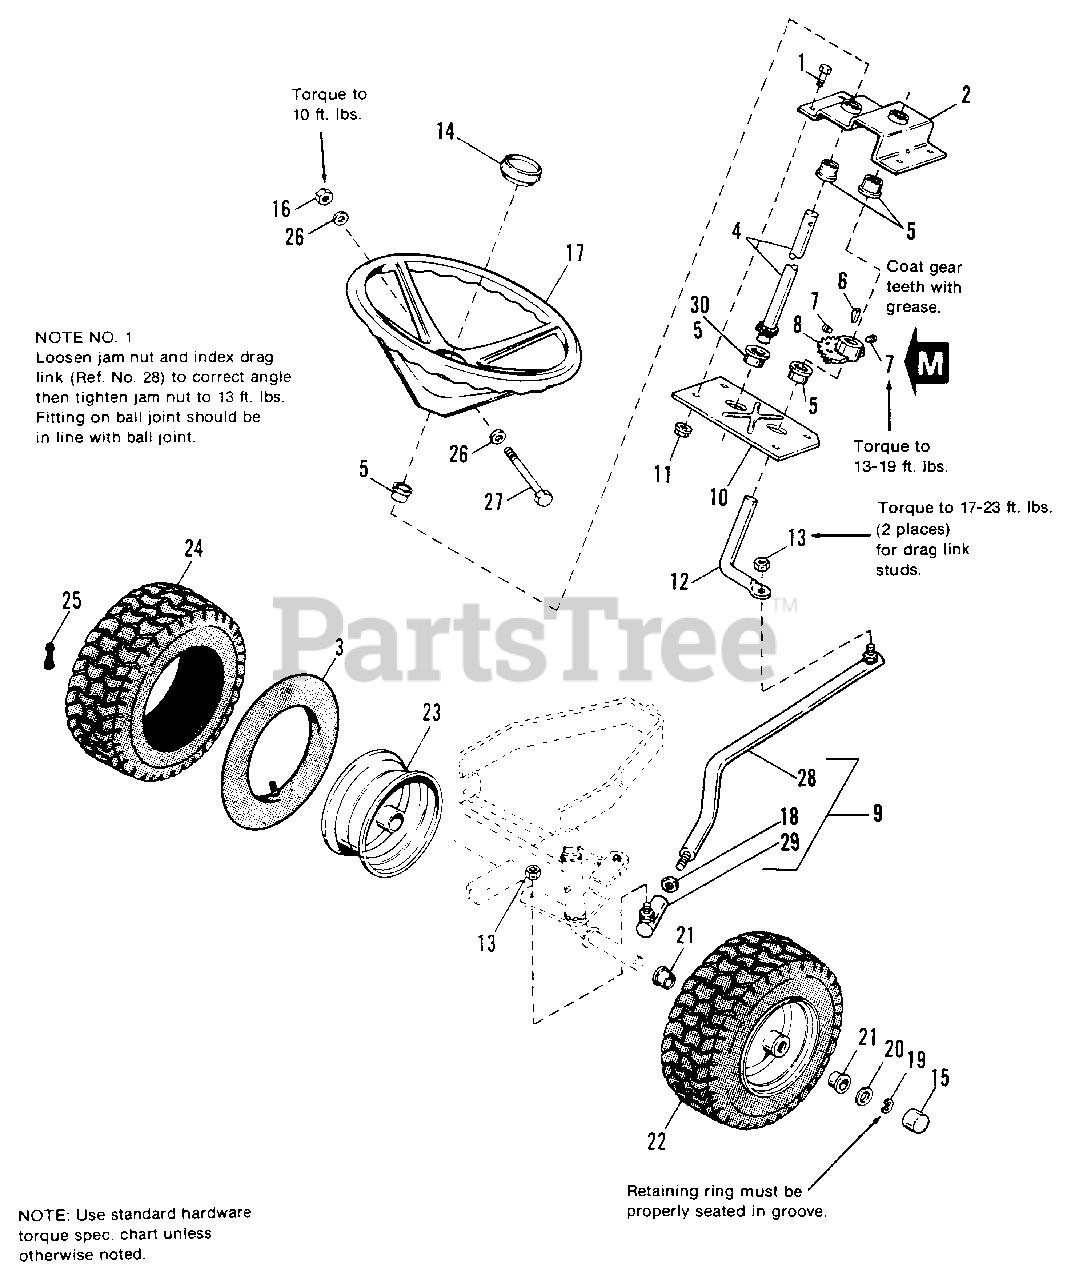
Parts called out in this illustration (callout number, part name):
1	CAPSCREW, 5/16-18 x 3/4
2	TOP PLATE, Steering
3	TUBE (For Service Only)
4	SHAFT ASSY., Steering (1690995, 1691029, 1691271, 1691325)
4	SHAFT ASSY., Steering (1691340 only)
7	SETSCREW, 5/16-18 x 1/2, Gr. 8
8	GEAR, Steering
9	LINK ASSY., Drag (Includes Ref. Nos. 18, 28 & 29)
10	BASE PLATE, Steering
11	LOCKNUT, Flange, Whiz, 5/16-18
12	ROD, Steering
13	LOCKNUT, Center, 3/8-24
14	CAP, Steering Wheel
15	CAP, Hub, Threaded
16	LOCKNUT, Hex, 5/16-18
17	WHEEL, Steering
18	NUT, Jam, 3/8-24
19	"E" RlNG, Ext., 3/4
22	WHEEL & TIRE ASSY., 15 x 6.00-6 (1690995 & 1691029 only)
22	WHEEL & TIRE ASSY., 15 x 6.00-6, Turf Mate (1691271, 1691325, 1691340 only)
23	WHEEL ASSY. (Incl. Ref. No. 21, Qty. 2)
24	TIRE (Carlisle), 15 x 6.00-6 (1690995, 1691029 only)
24	TIE (Carlisle), 15 x 6.00-6 (Turf Mate)(1691271, 1691325, 1691340 only)
25	STEM, Valve
26	WASHER, Plain, 5/16
27	BOLT, Hex, 5/16-18 x 3-1/2
29	BALL JOINT ASSY.
30	BUSHING, (1691340 only)
